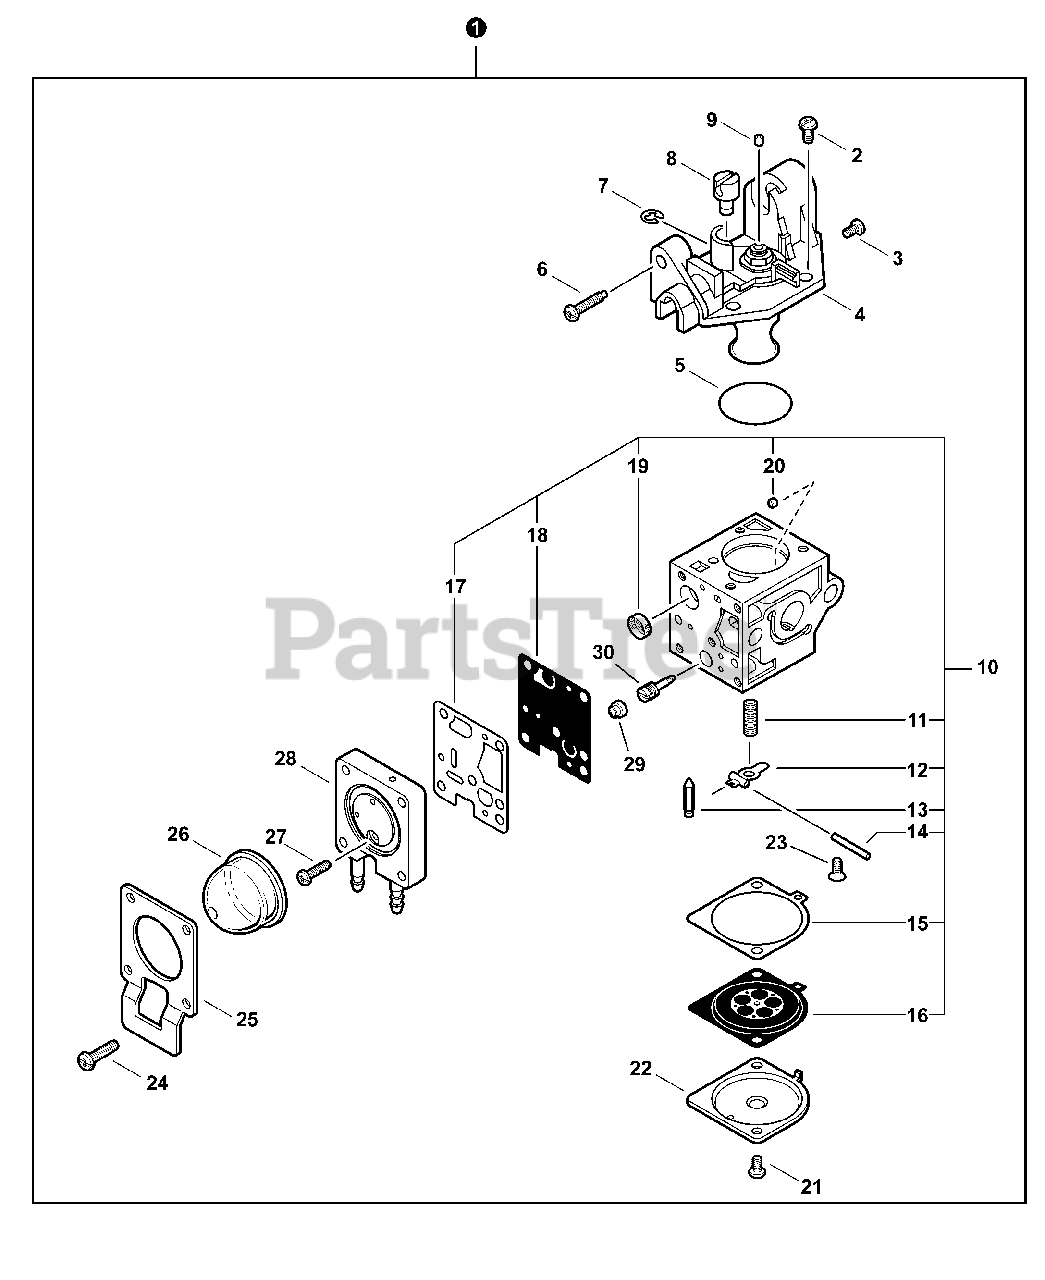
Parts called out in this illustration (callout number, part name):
1	CARBURETOR -- RB-K91
4	ROTOR COVER ASSY
6	SCREW, IDLE ADJUST
7	RING, RETAINING
10	REPAIR KIT
11	SPRING, METERING LEVER
12	LEVER, METERING
13	VALVE, INLET NEEDLE
14	PIN, METERING LEVER
15	GASKET, DIAPHRAGM
16	DIAPHRAGM, METERING
17	GASKET, PUMP
18	DIAPHRAGM, PUMP
19	STRAINER
20	GUIDE, ROLLER
22	COVER, METERING
23	SCREW, METERING LEVER PIN
24	SCREW, PURGE BULB RETAINER
25	RETAINER, PURGE BULB
26	BULB, PURGE
27	SCREW, PURGE BASE
28	BASE, PURGE
30	NEEDLE - HIGH SPEED
